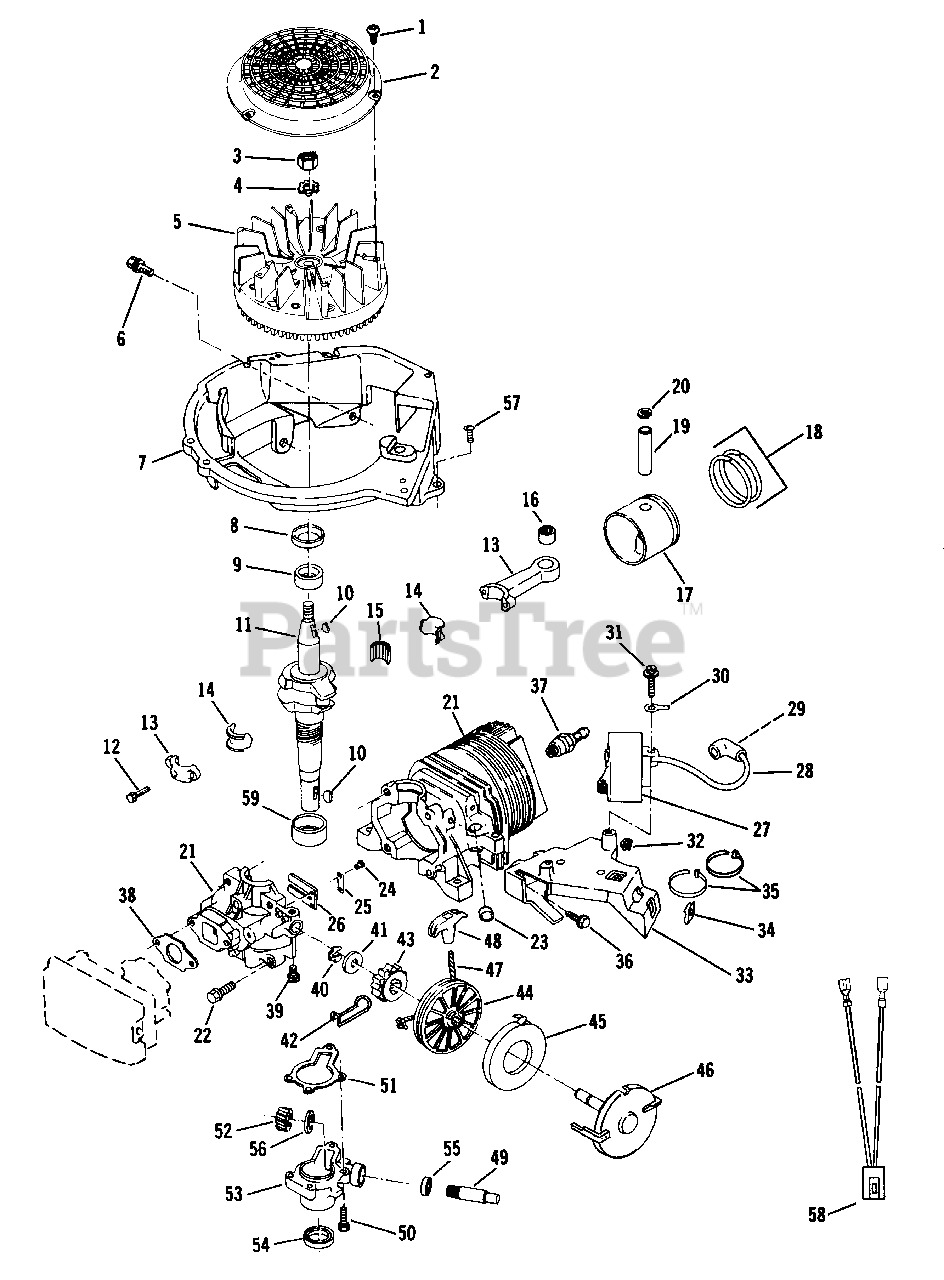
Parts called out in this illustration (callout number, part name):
1	Screw-Flywheel Screen
2	Screen-Flywheel
3	Nut-Flywheel
4	Lockwasher
5	Flywheel Assembly
6	Screw
7	Base-Shroud
8	Seal-Upper
9	Bearing-Upper
10	Key-Flywheel
11	Crankshaft
12	Screw
13	Connecting Rod Assembly
14	Liner Split
15	Noodle Bearing Set
16	Bearing assembly
17	Piston and Ring Set
18	Ring Set
19	Wrist Pin
20	Retaining Ring
21	Cylinder and Crankcase Cotter assembly
22	Screw-Cover to Crankcase
23	Plug
24	Screw-Reed to C'case Cover
25	Plate-Reod-Hold Down
26	Reed
27	C.D.D. Ignition Module and Lead. Assembly
28	High Tension Lead and Cover Assembly
29	Spring Terminal
30	Terminal-Ground Lead
31	6 Screw-C.D. Mounting
32	Grommet-C.D. Bracket
33	Bracket-Ignition Mtg.
34	Clip-"U"
35	Tie Strap
36	Screw
37	Spark Plug
38	Gasket-Carb. to Crankcase Cover
39	Set Screw-Starter Assembly
40	Retainer
41	Washer
42	Spring-Drag
43	Pinion
44	Pulley
45	Spring and Retainer Assembly
46	Cup and Pin Assembly
47	Rope
48	Handle-Starter
49	Driveshaft
50	Screw-Gear Box
51	Gasket-Gear Box
52	Gear
53	Gear Box Assembly
54	Oil Seal-Crankshaft
55	Seal-Driveshaft
56	Washer-Thrust
57	Screw-Shd. Base to C.D. Brkt.
58	Wire Harness-Engine
59	Bearing-Lower
